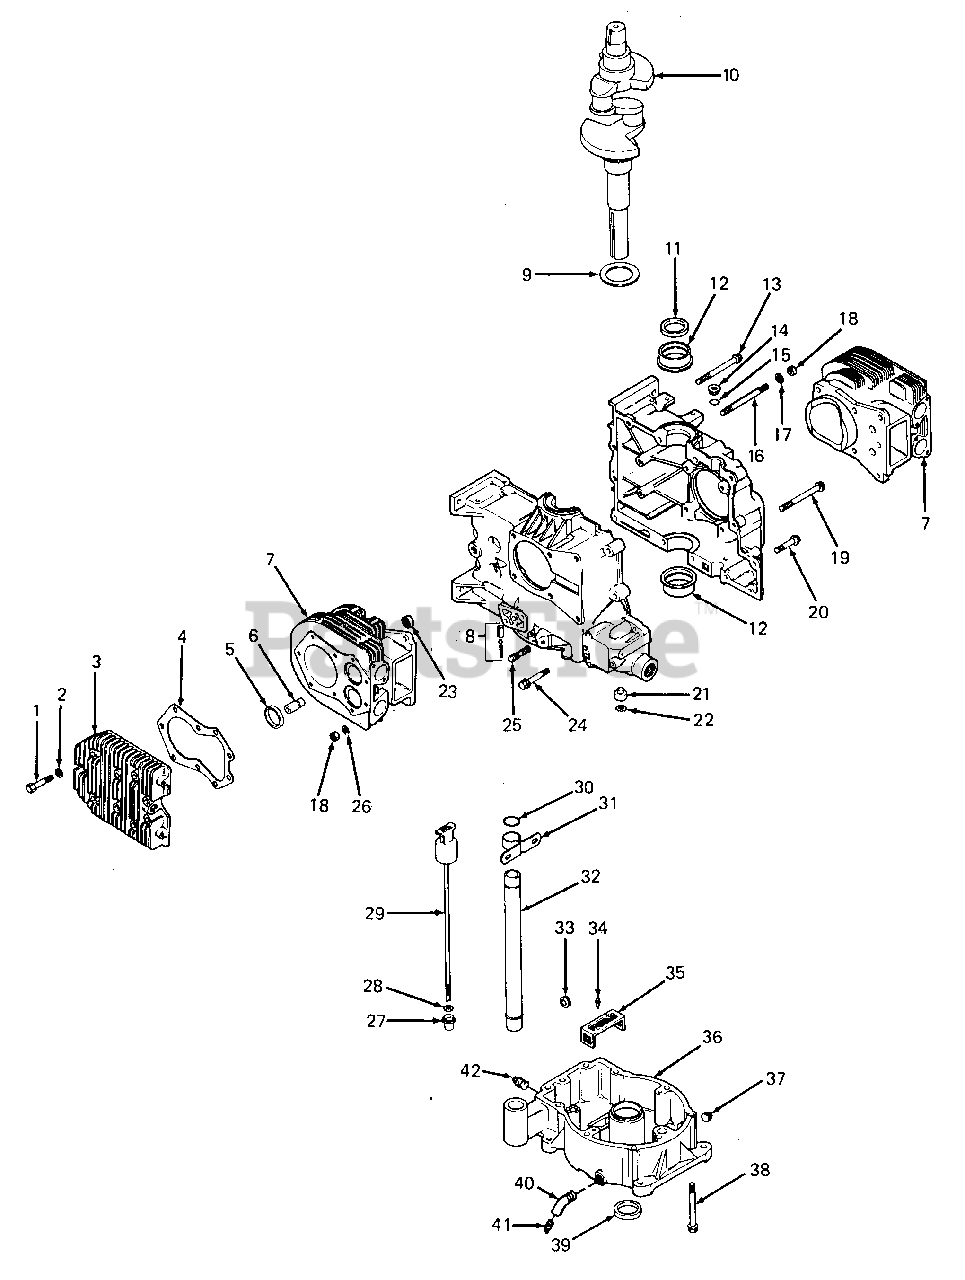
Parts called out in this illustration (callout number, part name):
1	Screw, Hex Hd, 5/16-18 X 1-1/2
2	Washer, Plain, 5/16
3	Head, Cylinder
4	Gasket, Cylinder Head
5	Insert, Valve Seat
6	Valve, Guide
7	Barrel, Cylinder Assy
8	Oil Relief Kit
9	Washer, Thrust, .119/.122
10	Crankshaft, 3-5/32 X 1 in. Tapped PTO
11	Seal, Front Oil
12	Bearing, Sleeve, Std
13	Screw, Hex Flange, 5/16-18 X 3-1/2
14	Plug, 3/4 in. O.D.
16	Stud, 5/16-18 X 4-1/8
17	Washer, Plain
18	Nut, Hex, 5/16-18
19	Screw, Hex Flange, 3/8-16 X 3-5/8
20	Screw, Hex Flange, 5/16-18 X 1-1/2
21	Shaft, Governor
22	Ring, Retaining
23	Bushing, Locating
24	Screw, Hex Flange, 5/16-18 X 2
25	Stud, Step, 5/16-18 X 3/4, 3/8-16 X 5/8, 2 in. Lg
26	Washer, Flat, 5/16
27	Seal, Rubber
28	Washer, Plain, 5/16
29	Dipstick, 13-1/2 in. Blade
31	Bracket, Oil Tube Support
32	Tube, Oil Fill, 11-7/8
33	Plug, Hex Ctsk, 3/4 NPTF
34	Screw, Hex Wash Hd, 10-32 X 7/16
35	Filter, Oil Pickup
36	Pan, Oil
37	Plug, Sq Solid Hd, 3/8 NPTF
38	Screw, Hex Wash Hd, 5/16-18 X 3-1/4
39	Seal, Rear Oil
40	Pipe, Oil Drain
41	Plug, Pipe, H-Hd Auto, 1/4-18 ZNP
42	Plug, Hex Ctsk, 1/4 NPTF
